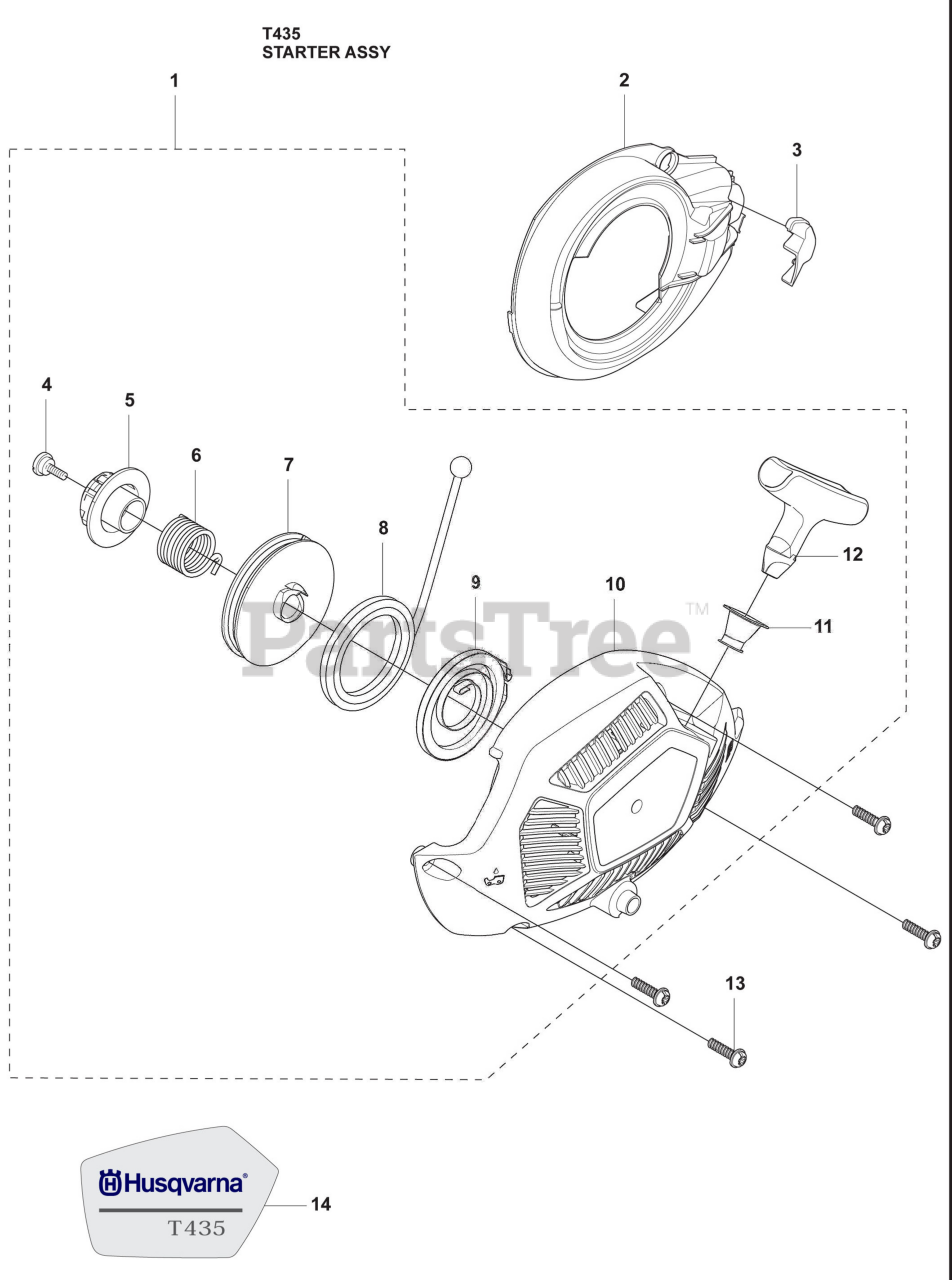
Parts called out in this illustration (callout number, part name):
1	Starter assy
2	Cover flywheel
4	Screw
5	Cam, plate
9	Starter spring
10	Starter case
11	Rope guide
12	Starter handle
14	Decal, startercover
